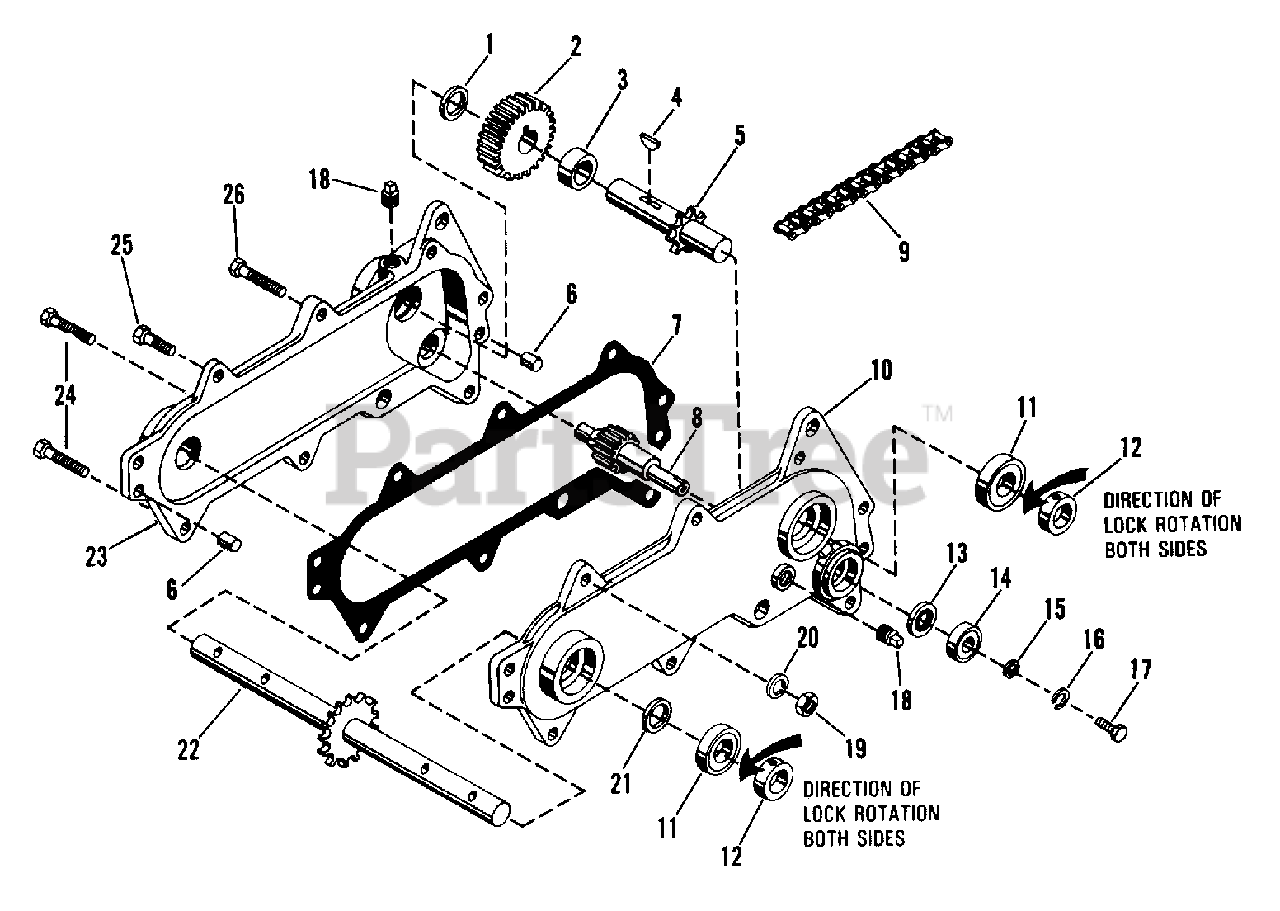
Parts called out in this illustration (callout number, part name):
1	SPACER 1.006X1.438X.467
2	GEAR 47T
3	SPACER 1.137X1.50X.656
4	KEY-WDRF .25X1.00X.438 SAE15
5	DRIVEN SHAFT
6	DOWEL PIN
8	DRIVE SHAFT
9	ROLLER CHAIN #60 44P
10	CHAIN CASE COVER
11	BRG-BALL 1.125X2MMX18MM
12	COLLAR-BEARING
13	SEAL 1.00X1.50X.188
14	BRG-BALL .750X1.781X.61
15	WSHR-FL-STL .328X1.0X.094
16	WSHR-LK .312X.097 PL HVY
17	BLT-HEX .31-18X.75 PL GR5
18	PIPE PLUG
19	NUT-HEX .312-18
21	SEAL 1.125X1.874X.250
22	TINE SHAFT
23	CHAIN CASE
24	BLT-HEX .31-18X1.75 GR5
25	BLT-HEX .31-18X1.50 PL GR5
26	BLT-HEX .31-18X2.00 PL GR5
27	CHAIN CASE ASSEMBLY
